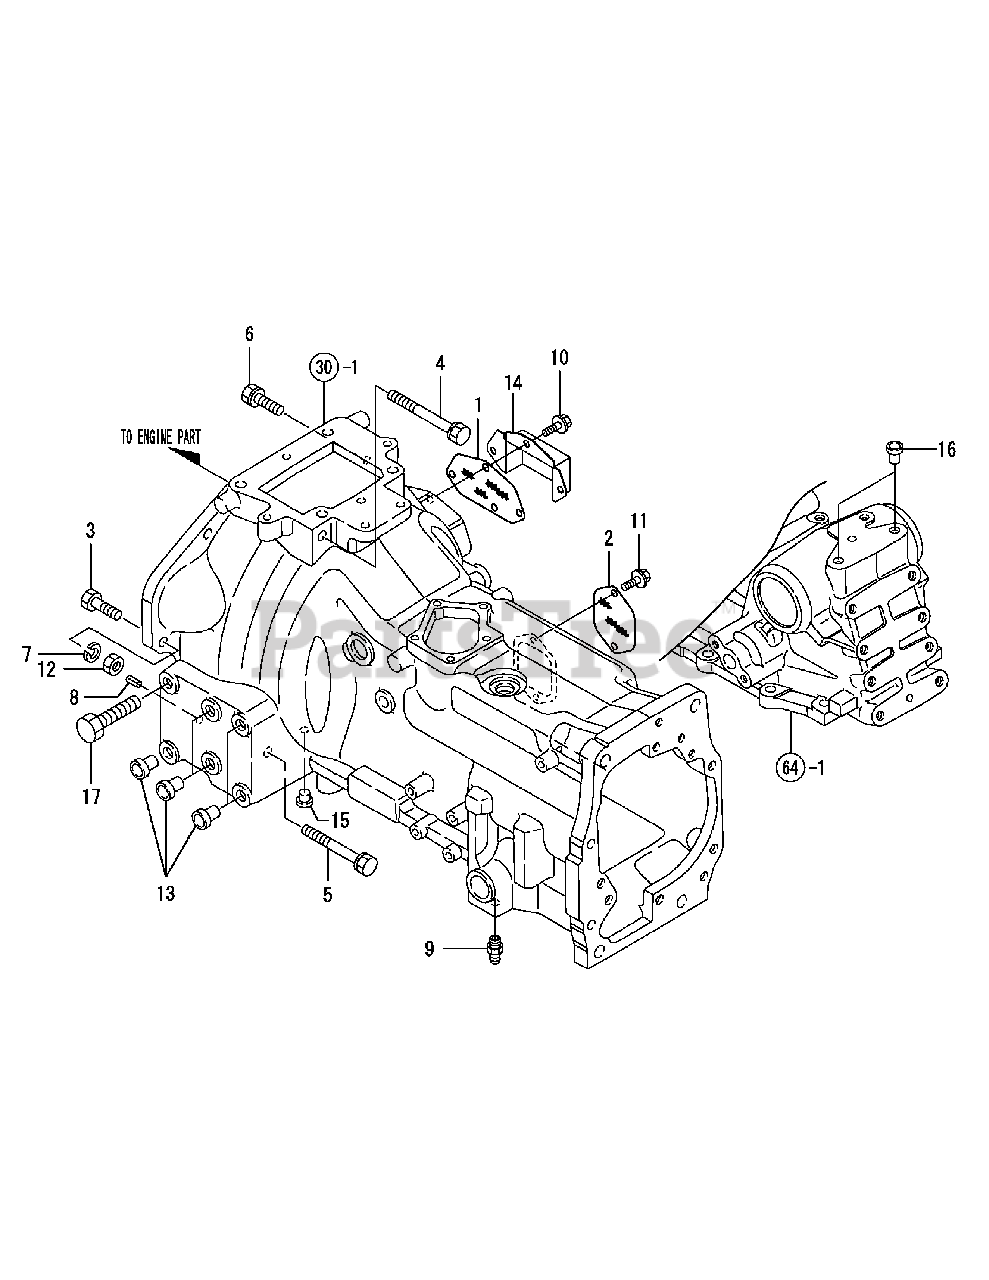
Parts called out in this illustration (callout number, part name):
1	COVER, HOUSING
4	BOLT W/WASHER 12X170
5	BOLT,W/WASHER 12X100
6	BOLT W/WASHER 12X30
7	SPRING WASHER 12
8	SPRING PIN 8X18
9	NIPPLE PT1/8,GREASE
10	BOLT M 8X 12 PLATED
11	BOLT M 8X 12 PLATED
14	COVER, HOUSING
17	BOLT M16 X 30 PLATED
